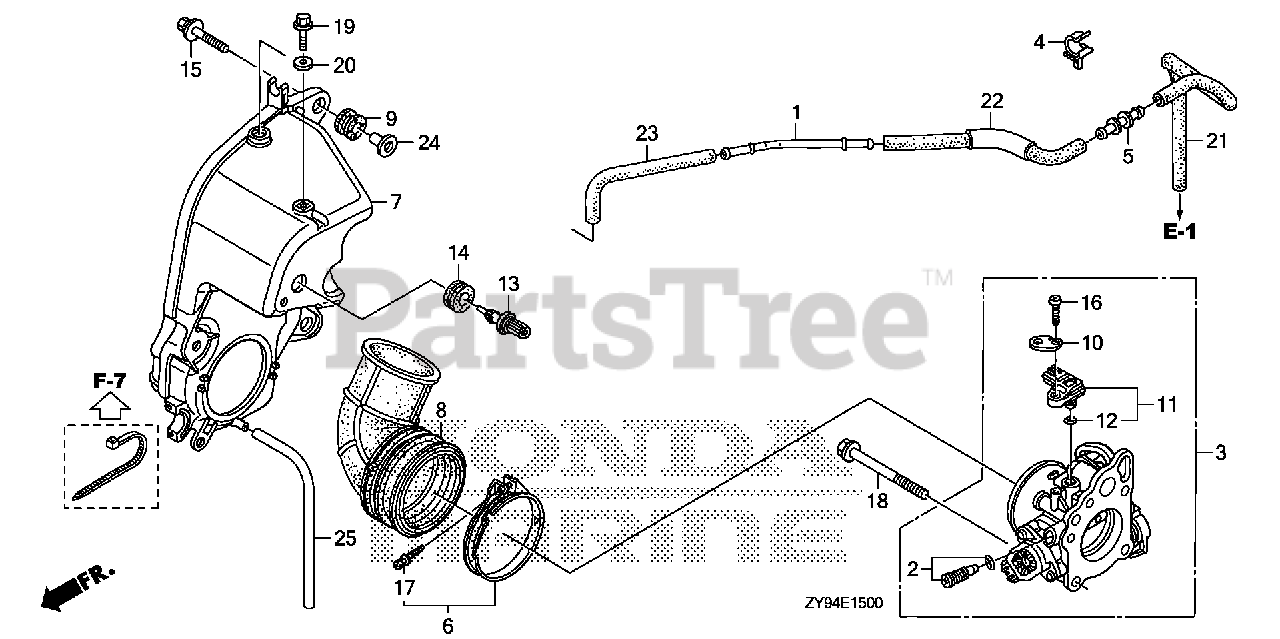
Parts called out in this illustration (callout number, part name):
1	PIPE, BREATHER
3	BODY ASSY., THROTTLE
4	CLAMP B, FUEL TUBE
5	JOINT, FUEL TUBE
6	BAND, AIR FLOW
7	CASE, MUFFLER
8	GROMMET, MUFFLER
9	GROMMET, ELECTRONIC PARTS CASE
10	BRACKET, SENSOR WIRE
11	SENSOR ASSY., MAP
13	SENSOR ASSY., AIR TEMPERATURE (MATSUSHITA DENSHI)
14	GROMMET, TA SENSOR
15	BOLT-WASHER (6X27) (CT200)
16	SCREW, PAN (5X18)
17	BOLT-WASHER (5X30)
18	BOLT, FLANGE (8X60)
19	BOLT, FLANGE (6X25) (SH)
20	WASHER, PLAIN (6MM)
21	TUBE A, BREATHER
22	TUBE B, BREATHER
23	TUBE C, BREATHER
24	COLLAR, MODULE IGNITION CONTROL CASE (CDI)
25	BULK HOSE, VINYL (4X7X8000) (95003-07(95003-07001-60M) (CARBURETOR NO.)
